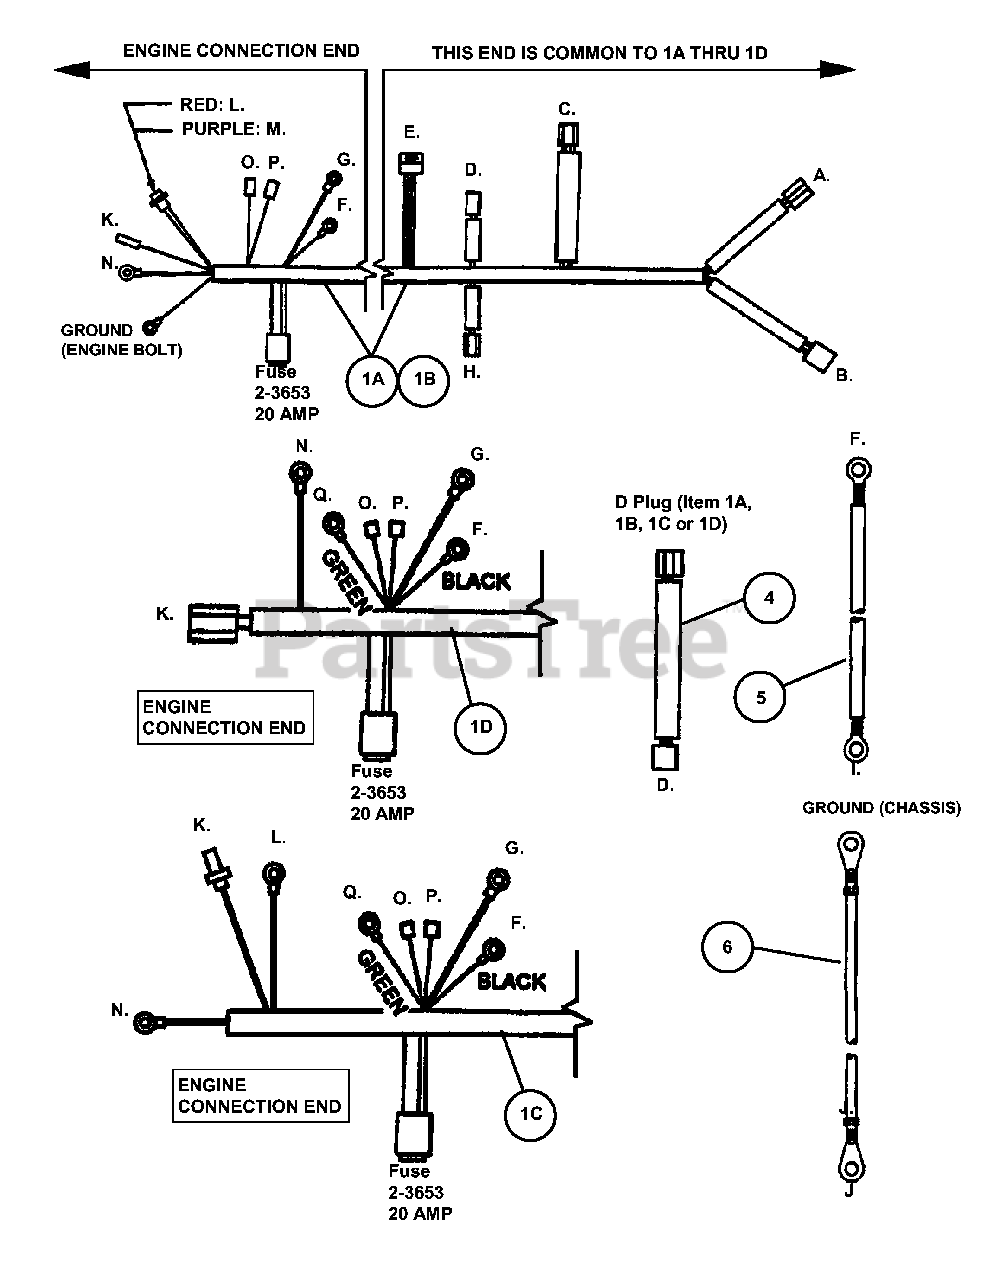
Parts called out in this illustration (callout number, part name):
1A	WIRING HARNESS
1B	WIRING HARNESS
1C	WIRING HARNESS
1D	WIRING HARNESS
4	WIRING HARNESS, Warner Clutch
5	WIRE, Positive, 13"
6	WIRE, Negative, 14"
